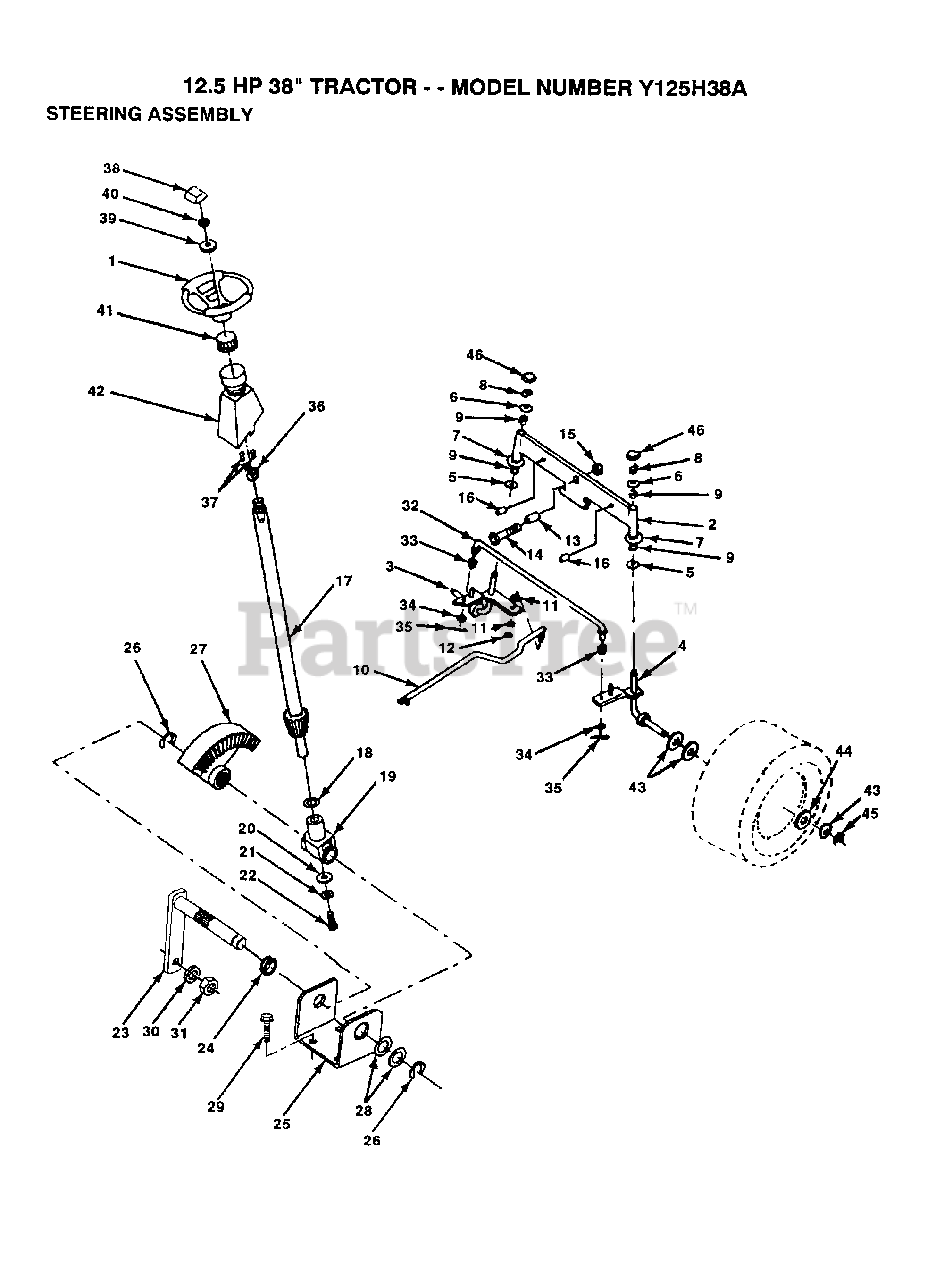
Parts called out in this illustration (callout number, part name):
3	SPINDLE LH
4	SPINDLE RH
5	WASHER .T
6	WASHER
7	WASHER
8	RING
9	COL. SRTG. BEAR.
11	LOCKWASHER
13	BEARING
14	BOLT HEX 5/8-11
16	AXLE PIN
17	SHAFT ASM
18	THRUST WASHER
19	SUPPORT.SHAFT
21	LOCKWASHER
22	"SCREW,SPECIAL"
24	NYLINER T
25	"BRKT,STEERING"
26	RING
28	WASHER .T
29	SCREW
30	LOCKWASHER
32	TIE ROD
33	BUSHING.DRAGLINK
34	WASHER
35	COTTER PIN
38	INSERT STEERING
39	WASHER T
40	GRIPCO NUT
41	ADAPTER-WHEEL LT
42	BOOT STR SHAFT
43	WASHER
44	WASHER
45	RING
46	CAP
